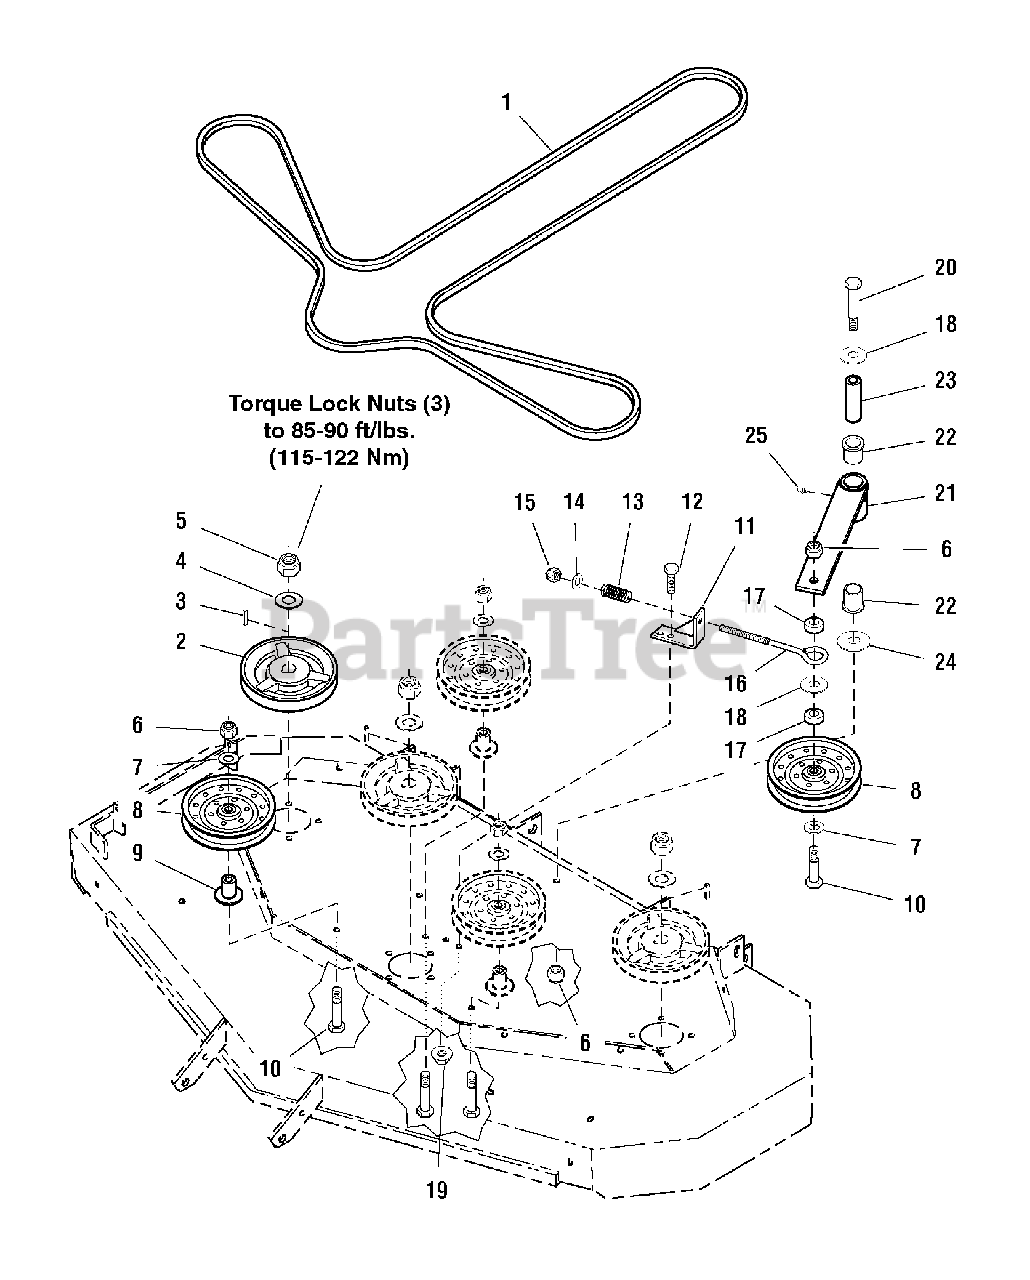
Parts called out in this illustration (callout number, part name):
1	BELT, 5V, 175.90EL, LG ARAMID, WRPD, RC
2	SPINDLE PULLEY
3	KEY, 1/4 x 1-1/4
4	WASHER, Spring
5	NUT, Hex, Nylon Lock, 5/8-18
6	NUT, Hex, Nylon Lock, 1/2-13
7	WASHER, 1/2
8	*PULLEY, FLAT IDLER, 6-3/4"
9	WELD, MOUNT, IDLER
10	CAPSCREW, Hex Hd, 1/2-13 x 3
11	SPRING ANCHOR
12	CAPSCREW, Hex Hd, 3/8-16 x 1
13	SPRING, Compression
14	WASHER, 3/8
15	NUT, Hex, Nylon Lock, 3/8-16
17	SPACER, .52 x 1.00 x .44
18	WASHER, USS, 1/2
19	NUT, Hex, Serrated Flange, 3/8-16
20	CAPSCREW, Hex Hd, 1/2-13 x 4-1/2
22	BUSHING, Flange
23	IDLER ARM PIVOT SHAFT
24	WASHER, 5/8
25	GREASE FITTING
